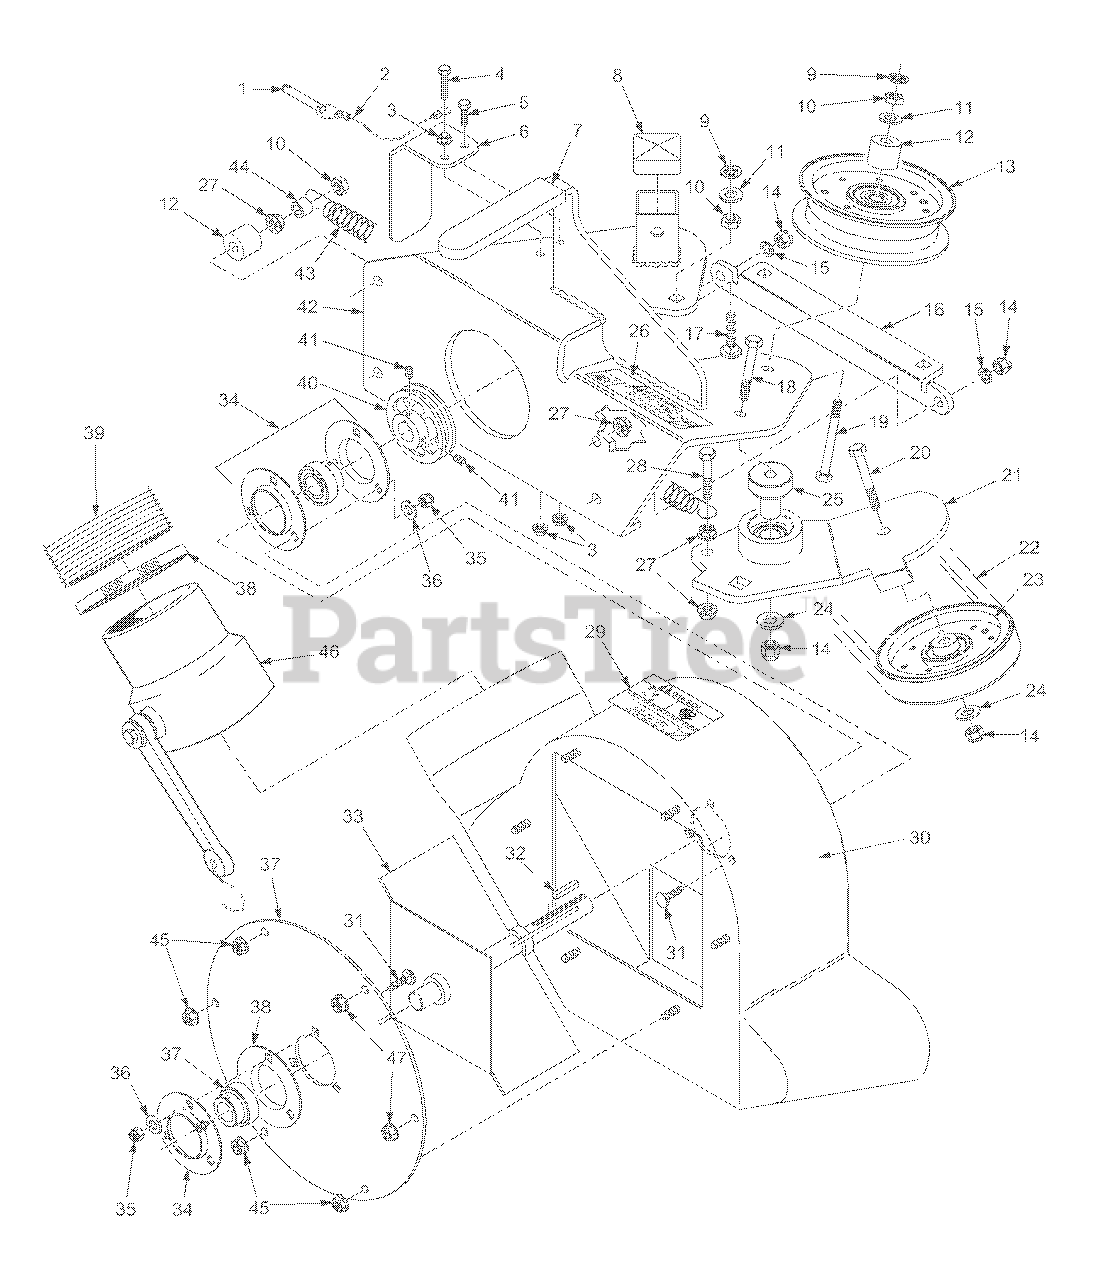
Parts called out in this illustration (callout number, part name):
1	Pin, Ring 2-1/4" Long
2	Lanyard, Deck Height Pin
3	Nut, Serr. Flange 1/4-20
4	Bolt, Hex Head 1/4-20 x 1-1/4"
5	Bolt, Hex Head 1/4-20 x 3/4"
6	Belt Cover, Rear
7	Grip, Blower Lever
8	Cap, Square
9	Nut, Push On 3/8 Thread
10	Lock Nut, 3/8-16
11	Flatwasher, 3/8-.391 x .938 x .105
12	Spacer
13	Pulley, Idler 3" Dia. - 52" Cutter Deck
14	Nut, Elastic Stop 3/8-16
15	Lockwasher, 3/8-16
16	Plate, Catch Mounting
17	Bolt, Carr. 3/8-16 x 1-1/2"
18	Bolt, Hex Head 3/8-16 x 3" - 52"
19	Bolt, Hex Head 3/8-16 x 3-1/2"
20	Bolt, Hex Head 3/8-16 x 1-3/4"
21	Idler Arm Assembly, GC-STT 52"
22	Belt, GC-STT 52"
23	Pulley, 3" O.D., GC-STT 52"
24	Washer, 3/8 Hardened
25	Pivot, Idler - 52"
26	Decal, Belt Cover
27	Nut, Serr. Flange 3/8-16
28	Bolt, Hex Head 3/8-16 x 1-1/2 Gr. 8
29	Decal, Danger
30	Blower Housing Assembly
31	Bolt, Carr. 5/16-18 x 3/4" Gr. 5
32	Key, 1/4 x 1/4 x 1-1/2"
33	Fan Weldment
34	Bearing Assembly
35	Nut, Elastic Stop 5/16-18
36	Flatwasher, 5/16-.344 x .688 x .065
37	Cover, Blower Housing
38	Clamp, 8-5/8" Max Dia.
39	Hose, 8.00" Dia. x 60.5" Long
40	Pulley, 4-3/4" O.D. - 1" Bore
41	Set Screw, 5/16-18 x 3/8"
42	Frame, Blower Mount - 52"
43	Spring, Main Drive
44	Spacer
45	Nut, Serr. Flange 5/16-18
46	Adapter w/Strap
